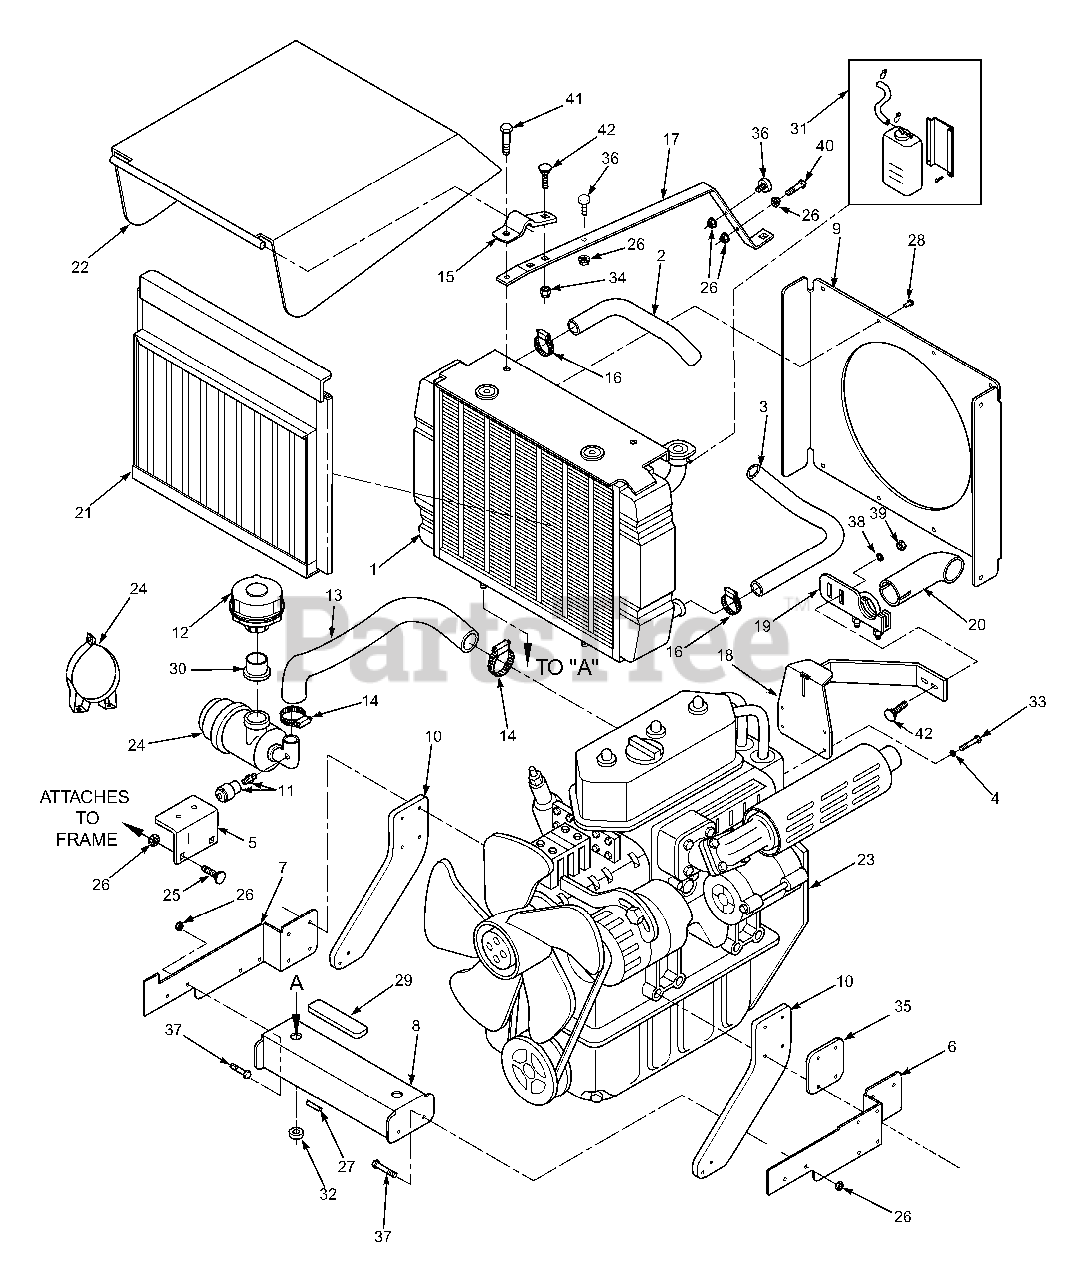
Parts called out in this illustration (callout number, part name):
1	Radiator
2	Hose, Upper Radiator
3	Hose, Lower Radiator
4	Lockwasher, 5/16 (.317 x .586 x .078) Helical Spring
5	Bracket, Air Cleaner
6	Bracket, Engine Mounting LH
7	Bracket, Engine Mounting RH
8	Bracket, Radiator Mounting
9	Shroud, Radiator
10	Plate, Engine Mounting
11	Indicator, Air Cleaner
12	Pre-Cleaner, Engine Air
13	Hose, Air Intake
14	Clamp, Hose (2.25" Dia.)
15	Hinge, Hood
16	Clamp, Hose (1.50" Dia.)
17	Bracket, Hood Support
18	Bracket, Exhaust Support
19	Clamp Weldment, Muffler (Clamp and Weldment)
20	Elbow, Exhaust
21	Screen, Debris
23	Engine, Briggs & Stratton 31 HP
24	Air Cleaner Assembly w/Mounting Band
25	Bolt, Carr. 5/16-18 x .75"
26	Nut, Serr. Flng 5/16-18
27	Pin, Rue Cotter 1/2" dia.
28	Rivet, Pop 1/8 x .294"
29	Pad, Radiator
30	Adaptor, Pre-Cleaner
31	Coolant Tank Assembly w/Hose
32	Spacer, Radiator
33	Bolt, Hex Head M8 x 20MM LG
34	Nut, 5/16-18 Elastic Stop
35	Engine Spacer
36	Bumper, Rubber
37	Bolt, Hex Head 5/16-18 x .75"
38	Flatwasher, 5/16 (.375 x .875 x .083)
39	Nut, 5/16-18 Elastic Stop
40	Bolt, Hex Head 5/16-18 x 1.50"
41	Bolt, Hex Head 5/16-18 x .75 Serrated Flange
42	Bolt, Carriage 5/16-18 x 1.0"
